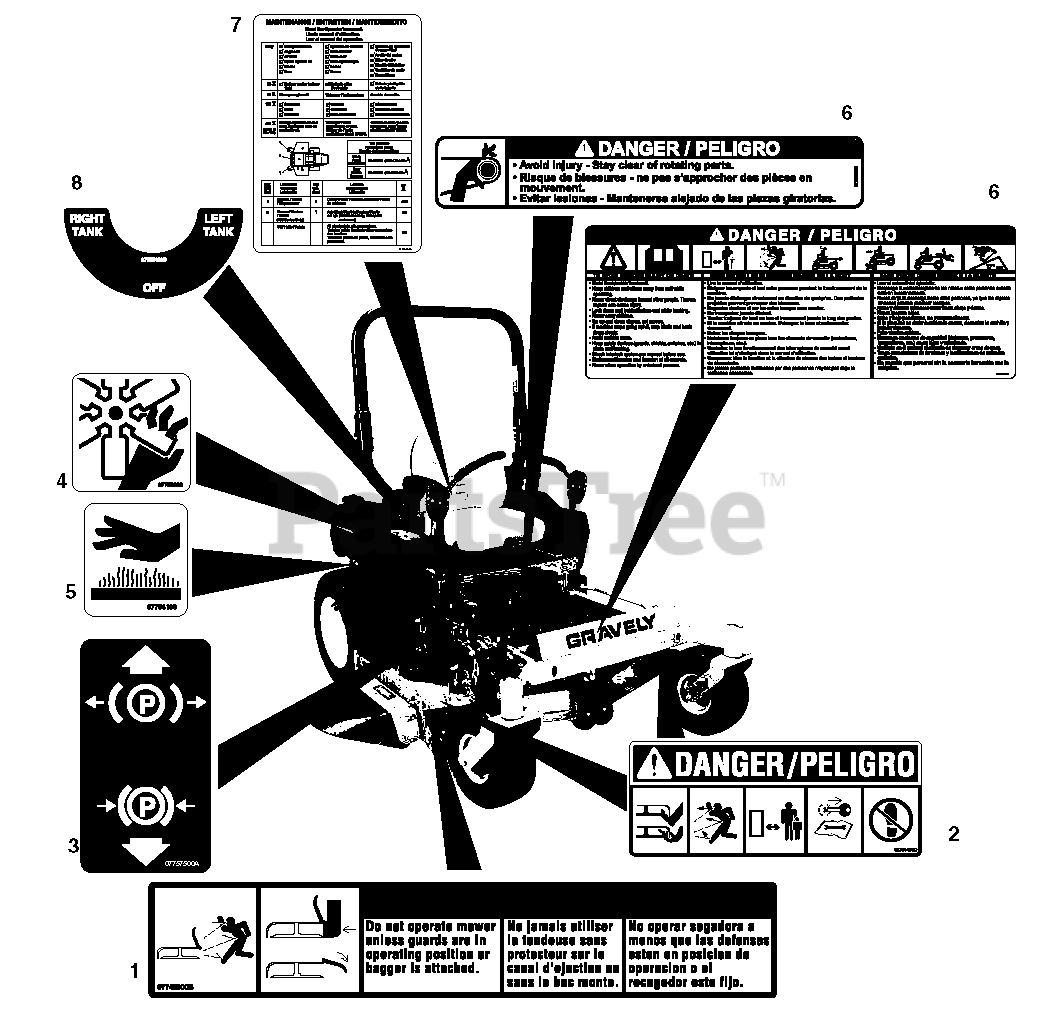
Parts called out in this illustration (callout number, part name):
1	Decal, Warning
2	Decal, Mower Pan Head Danger
3	Decal, Parking Brake Lever
4	Decal, Danger Fan
5	Decal, Hot Surface
6	Decal, Common Danger/Fuel
7	Decal, Maintenance Instructions
8	Decal, Fuel Control Valve
